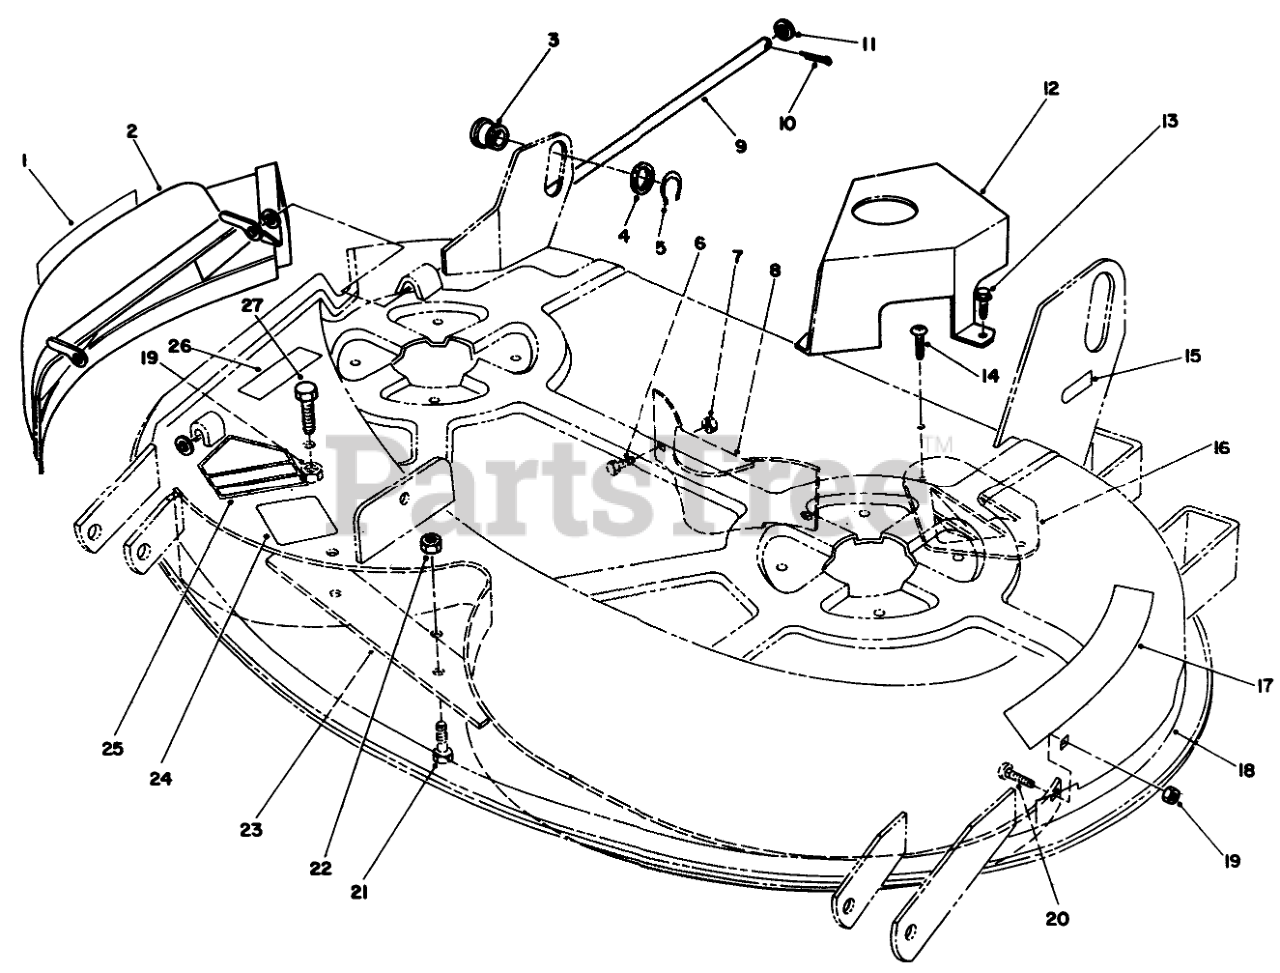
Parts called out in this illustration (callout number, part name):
1	DECAL-DANGER, THROWN OBJECT
2	Chute-Recycler
3	ROLLER-LIFT
4	Washer
5	Snap Ring
6	H H C S
7	Nut
8	Baffle-Rear
10	Cotter Pin
11	WASHER 5/16 SAE
12	Cover-Belt
13	SCREW-HWHTF
14	#8 X .625" PHILPS PAN H
15	Decal-Attach-A-Matic
16	PLATE-KICKER
17	DECAL-DANGER
18	DECAL-38" RECYCLER
19	Nut
20	Bolt
21	Bolt
22	NUT
23	Baffle-38"
24	Decal-Routing
25	DECAL-DANGER
26	DECAL-DANGER
27	H H C S
